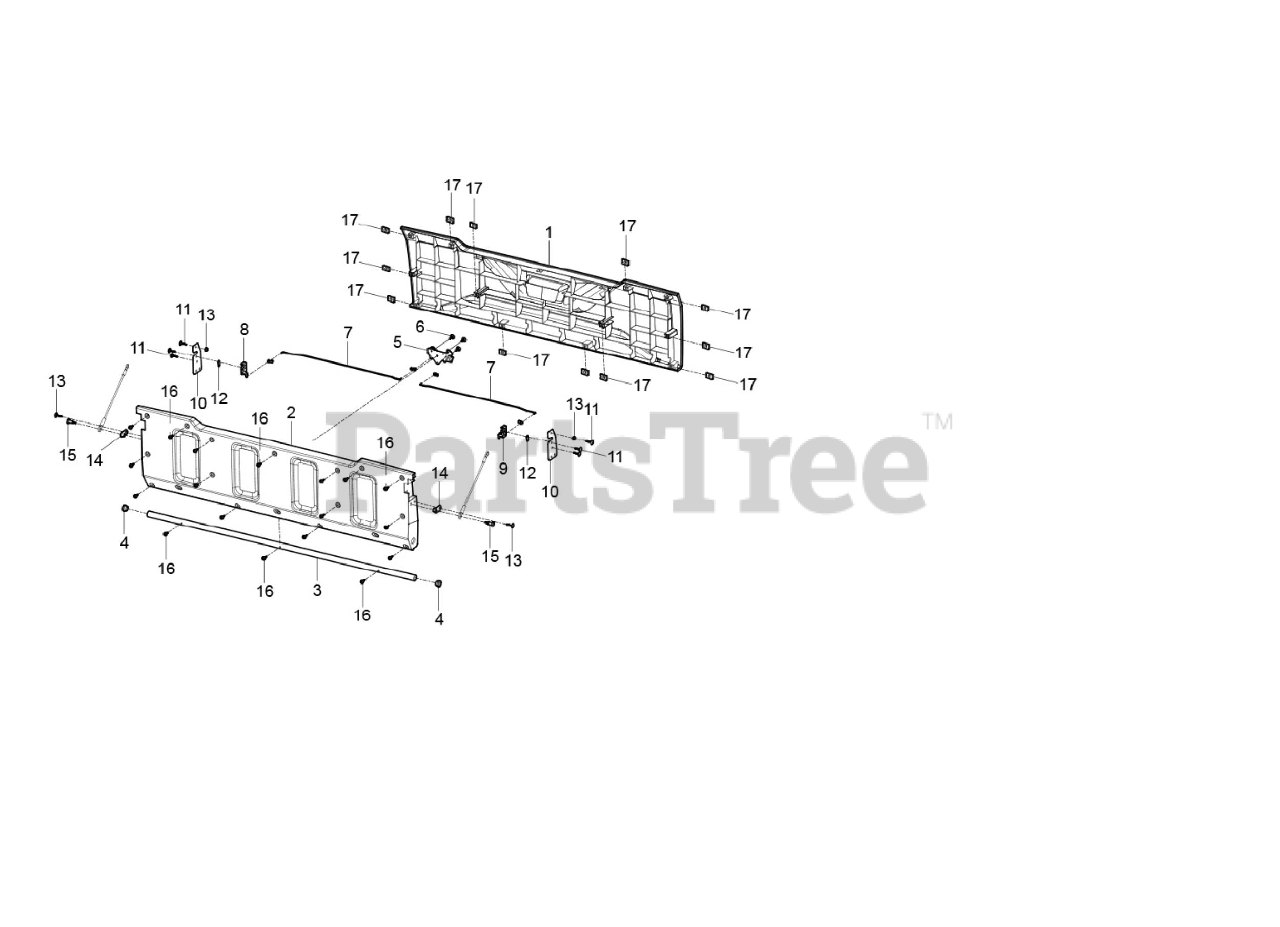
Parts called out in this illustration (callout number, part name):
1	CARGO BED DOOR
1	CARGO BED DOOR YELLOW
1	CARGO BED DOOR BLUE
1	CARGO BED DOOR BLACK
1	CARGO BED DOOR G2 CAMO
2	CARGO BED DOOR INSIDE PANEL
3	CARGO BED DOOR HINGE TUBE
4	BUSHING PLASTIC 10.5x18
5	CARGO BED LOCK ASSEMBLY
6	Cross Recessed Plate Head Screw M6x12
7	ROD - CARGO BED DOOR LOCK
8	CARGO BED DOOR LOCK KIT RH
9	CARGO BED DOOR LOCK KIT LH
10	DOOR LOCKING PLATE
11	Cross Large Plate Head Screw M6x16
12	Pan head screw with cross recess M6x30
13	HExAGON FLANGE HEAD NUT M6
14	DOOR LOCK STRAP PLATEDII
15	BOLT HExAGON SOCKET SHOULDER M8x18-10x9
16	Socket Hex Flat Head Bolt M6x16
17	CLAMP NUT M6x6
18	DOOR LOCK ADJUSTMENT GASKET
